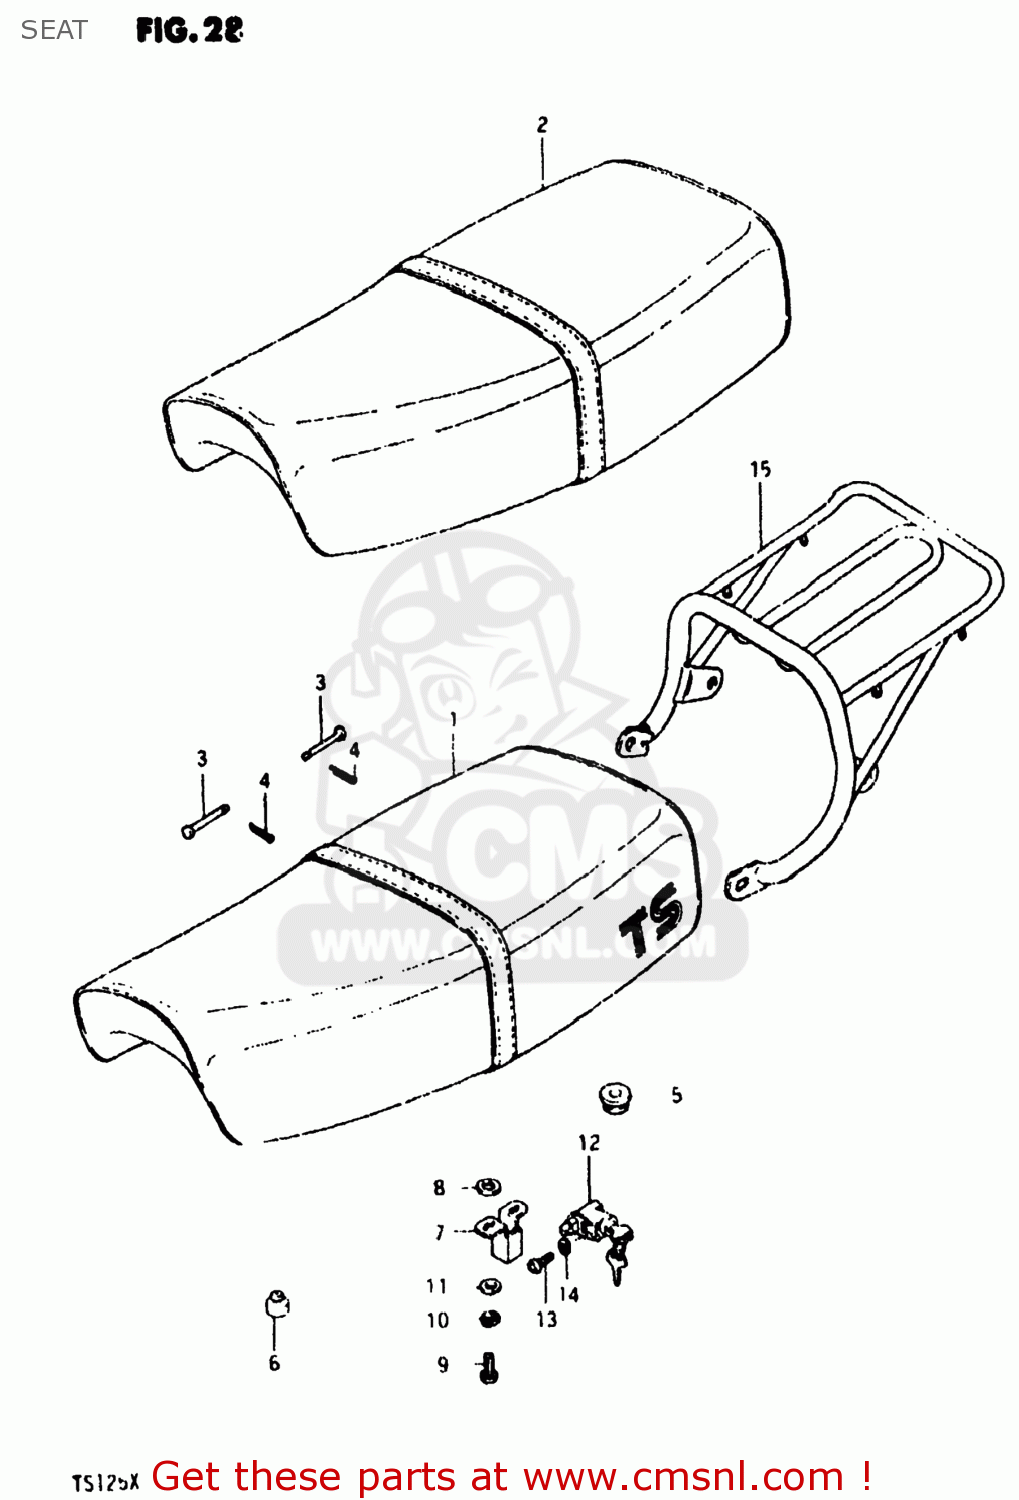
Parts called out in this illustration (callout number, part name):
1	SEAT ASSEMBLY
2	SEAT ASSEMBLY
3	PIN
4	PIN
5	CUSHION
6	CUSHION
7	PLATE,CLAMP GUIDE
8	WASHER(8.5X18X1)
9	NUT
10	LOCK WASHER
11	WASHER
12	LOCK ASSY,SEAT
13	SCREW
14	LOCK WASHER
15	CARRIER,SPORT
